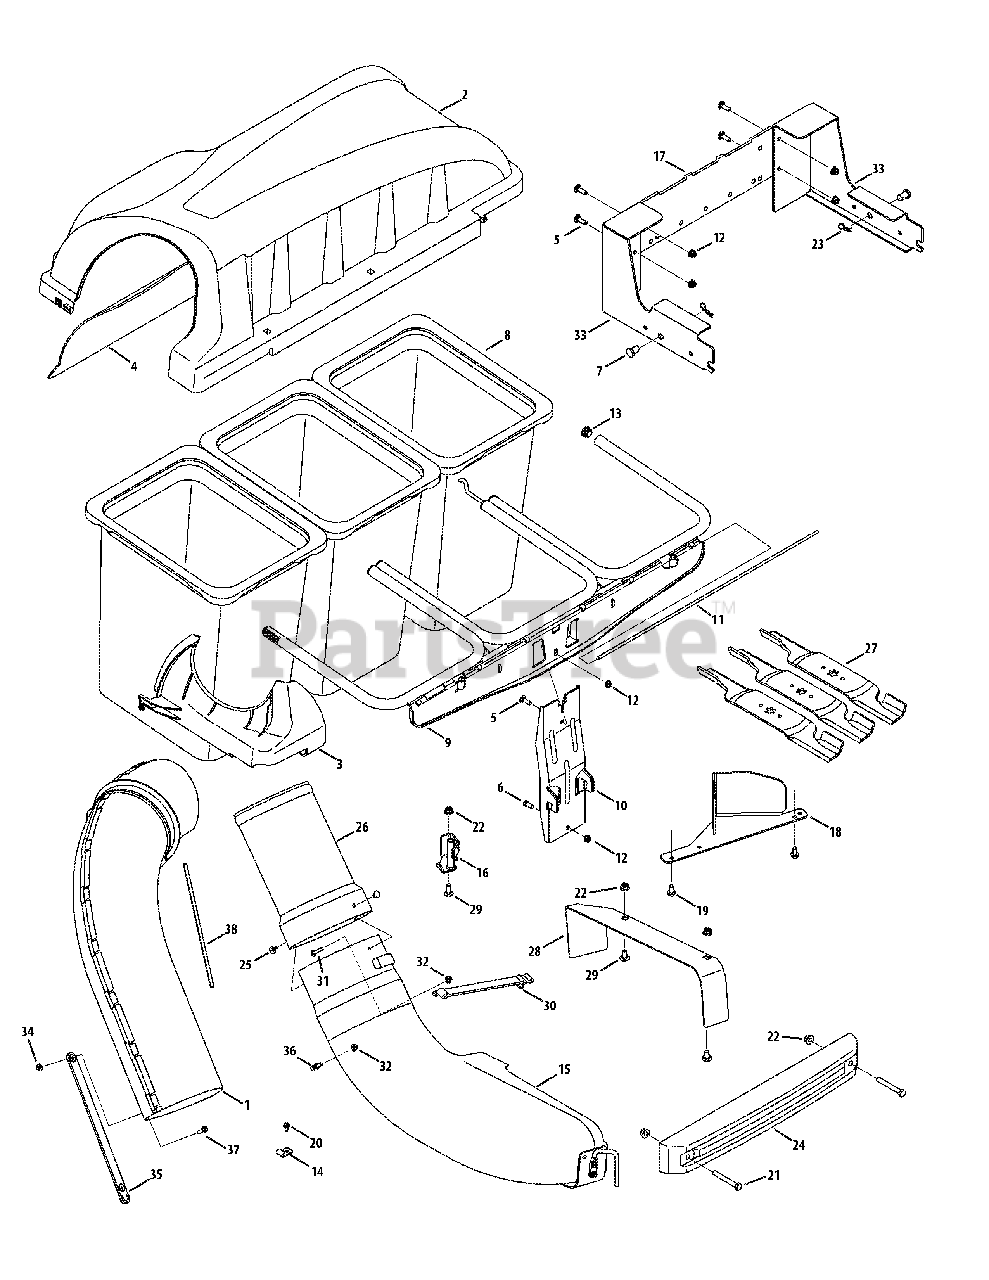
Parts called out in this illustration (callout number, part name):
1	Upper Chute Assembly
2	Triple Bagger Cover Assembly
3	Upper Chute Support
4	Bagger Cover Screen
5	Carriage Screw, 5/16-18 x 1.00"
6	Hex Head Screw, 5/16-18 x .75"
7	Clevis Pin, .50" Dia. x .78 Lg.
8	Grass-bag Assembly
9	Triple Bag Support Assembly
10	Vertical Support Bracket
11	Cover Hinge Pin
12	Flange Lock Nut, 5/16-18
13	End Plug
14	Retainer Hook
15	Discharge Chute Elbow
16	Chute Stop-Bracket
17	Universal Mounting Bracket
18	Deck Baffle
19	Tap Screw, 5/16 - 18 x .750
20	Tap Screw, 1/4 - 20 x .500
21	Hex Head Screw, 3/8 - 16 x 2.75
22	Flange Lock Nut, 3/8 - 16
23	Cotter Pin, .080 x 1.5625 Internal
24	RZT Bagger Weight
25	Ratchet Clip, .250
26	Bagger Chute Adapter, 7 In.
27	Blade, 18.50 Lg., High Lift
28	Chute Discharge Plate
29	Carriage Bolt, 3/8-16 x 1.00
30	Chute Strap
31	Hex Head Screw, 1/4-20 x .75
32	Flange Lock Nut, 1/4 - 20
33	RZT Mounting Assembly (Incl. Ref No. 17 & 33)
34	Flange Lock Nut, 1/4-20
35	Chute Strap
36	Grass-catcher Pin
37	Machine Screw, 1/4-20
38	Adhesive Strip
